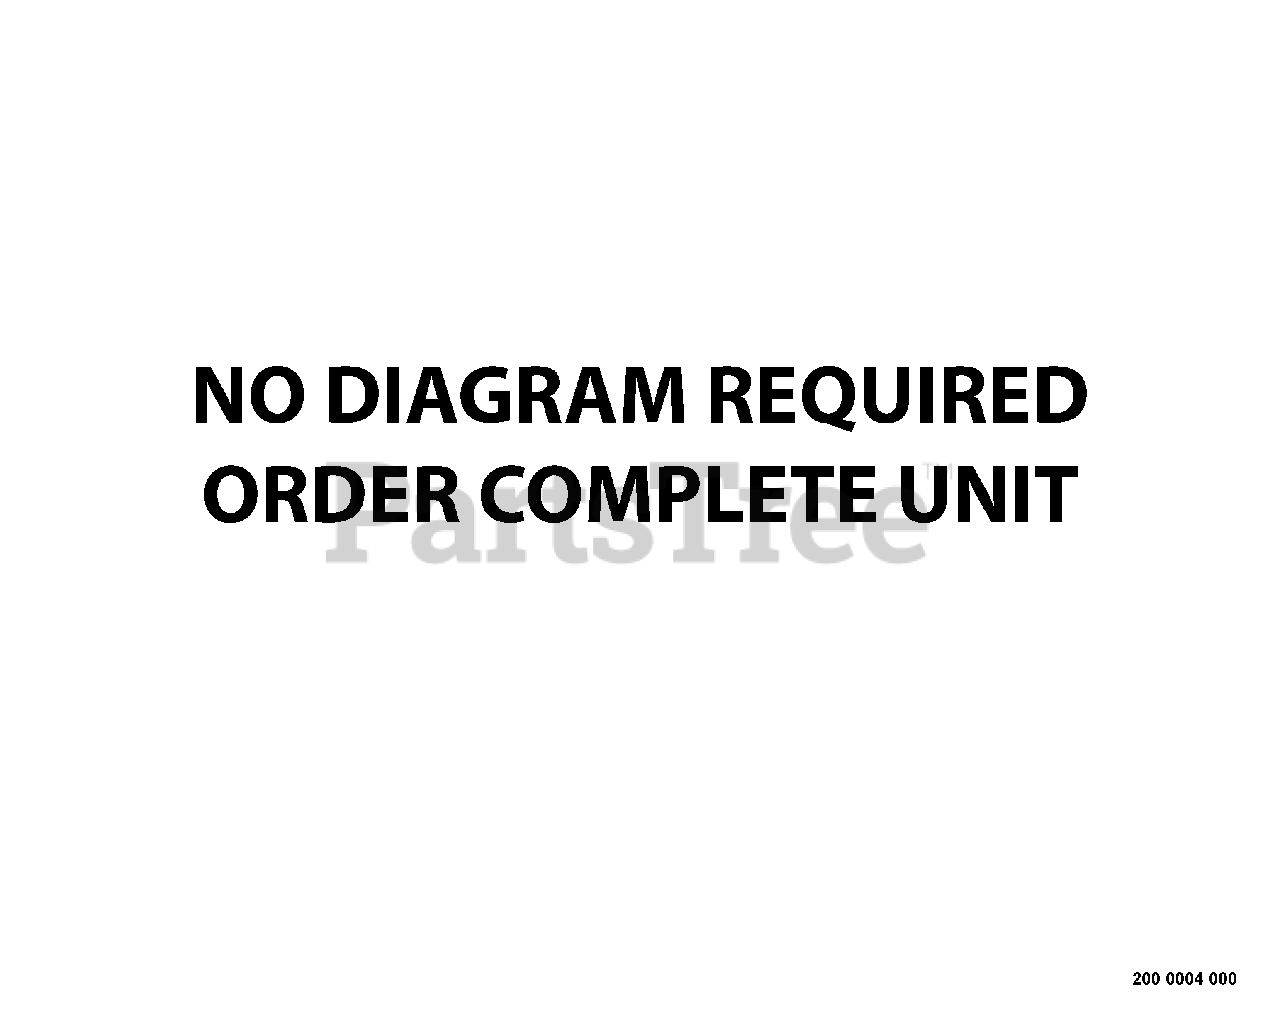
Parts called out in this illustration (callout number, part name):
1	GASKET KIT
2	GASKET, CRANKCASE
3	GASKET, EXHAUST
4	GASKET, CYLINDER
5	GASKET, INTAKE
6	SHIELD, INTAKE
7	GASKET, EXHAUST
8	SHIELD, EXHAUST
